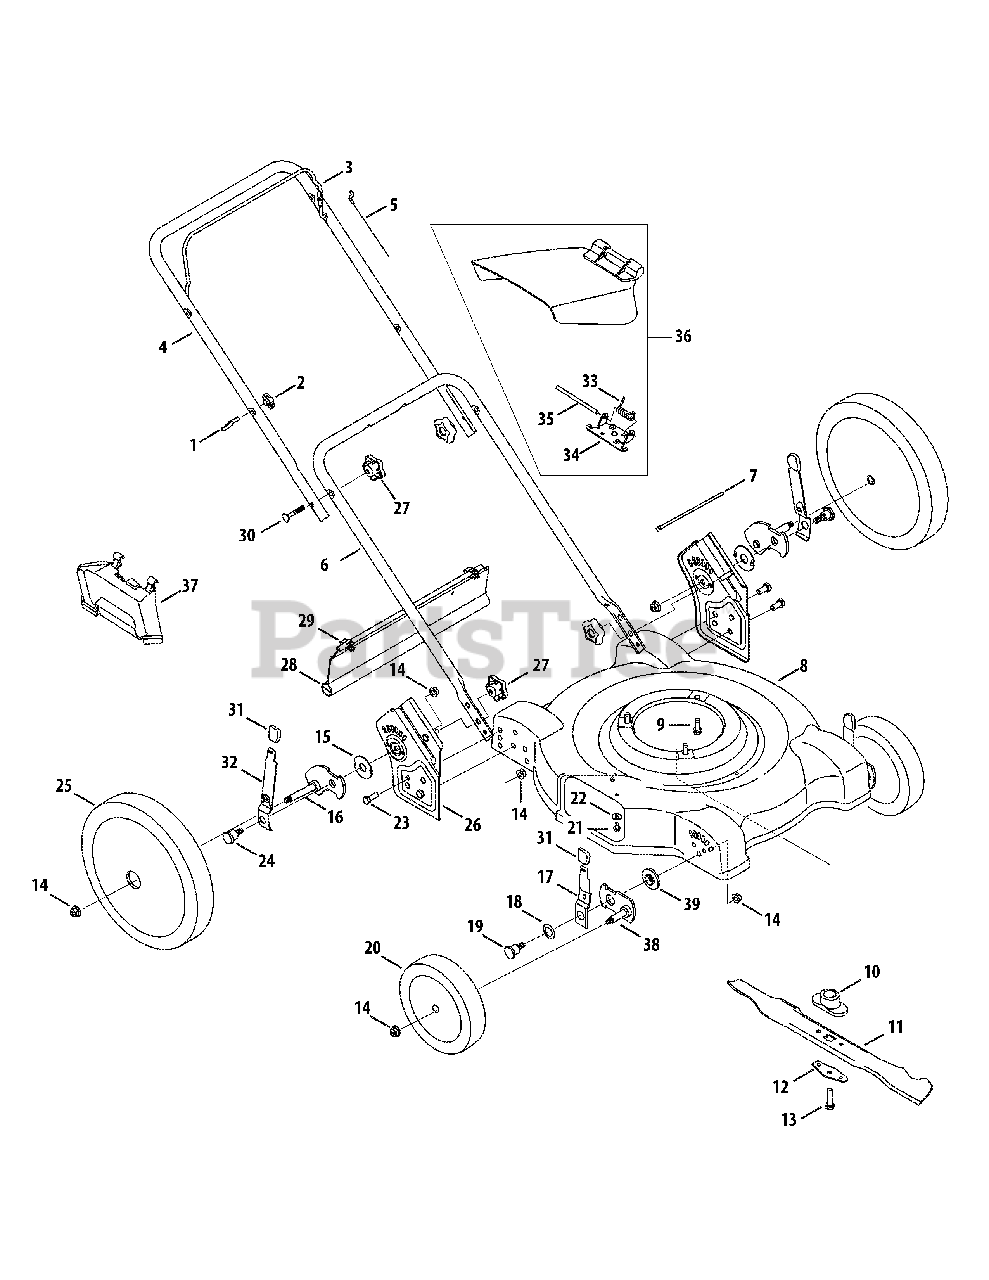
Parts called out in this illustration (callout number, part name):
1	Eye Bolt
2	Wing Nut
3	Blade Control Handle
4	Upper Handle
5	Control Cable
7	Cable Tie
8	Deck Assembly, 22"
9	TT Screw, 3/8-16 x 1.0
10	Blade Adapter
11	Mulching Blade, 22"
12	Blade Bell Support
13	Screw, 3/8-24 x 1.5
14	Lock Nut, 3/8-16
15	Thrust Bearing
16	Rear Pivot Arm - LH
16	Rear Pivot Arm - RH
17	Front Lever
18	Bell Washer, .760 OD x 1.25 OD
19	Shoulder Screw
20	Front Wheel
21	TT Screw, 1/4-20 x .5
22	Bell Washer, .265 ID x .75 OD
23	Screw, 3/8-16 x .75
24	Shoulder Screw
25	Rear Wheel
26	Handle Bracket Assembly, RH
26	Handle Bracket Assembly, LH
27	Star Knob
28	Trail Shield
29	Hinge Clip
30	Carriage Bolt, 5/16-18 x 2
31	Knob
32	Rear Lever
33	Torsion Spring
34	Chute Hinge
35	Hinge Pin
36	Hinged Chute Deflector Ass’y
37	Mulching Baffle
38	Front Pivot Arm
39	Height Adjuster Bearing
